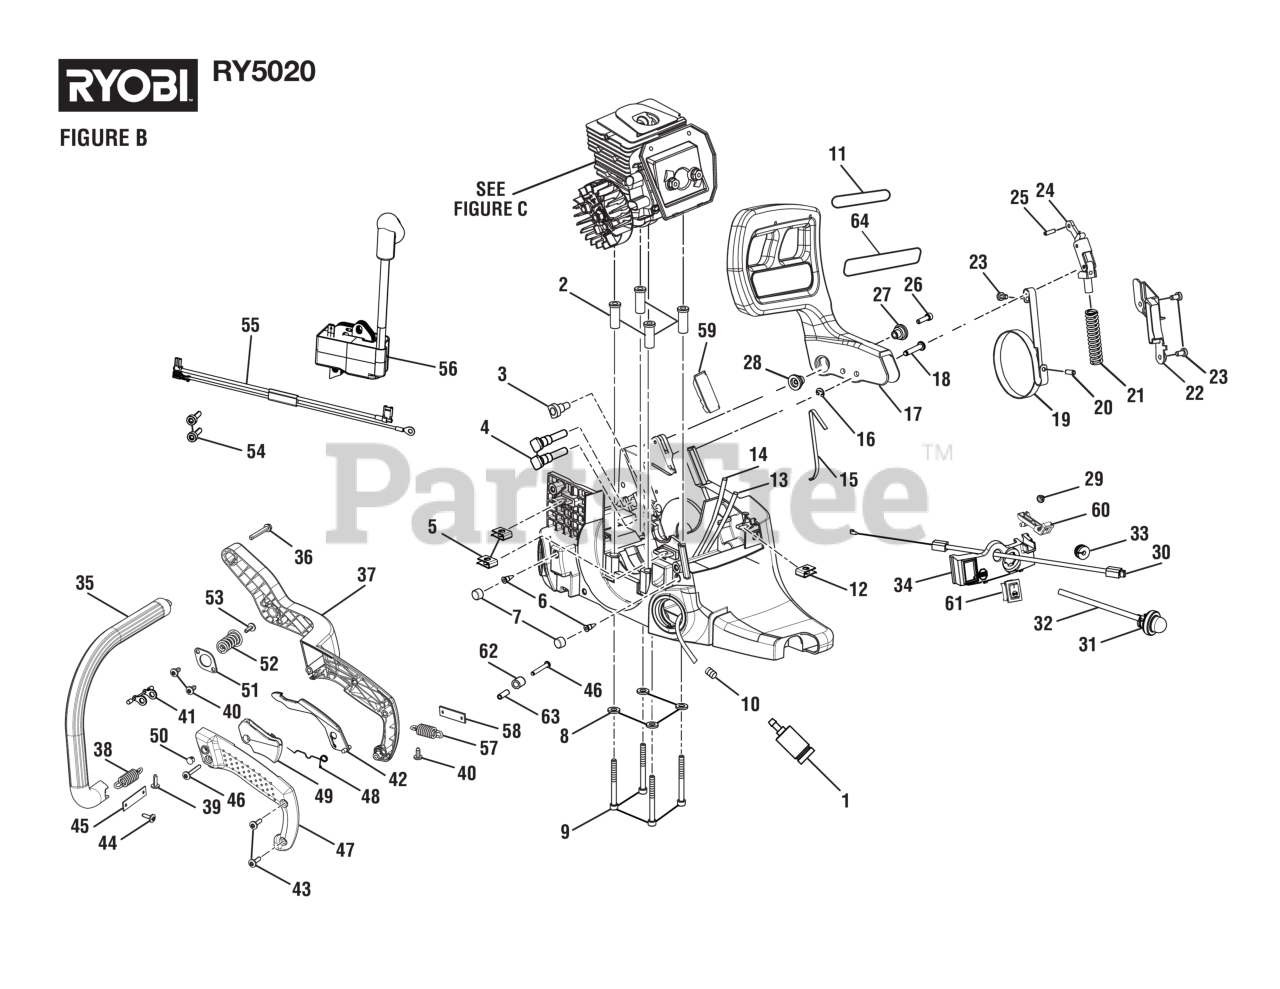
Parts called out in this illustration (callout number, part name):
1	Fuel Filter
2	Spacer Insert
3	GROMMET, OIL OUTLET
4	Control Panel, Black
5	Speed Nut ("U"-type)
6	Front Handle, Black
7	Front Handle, Gray
8	Washer (ID5.8 x OD11.5 x 1.7t)
9	Screw (10-24 X 2 in. Soc. Cap Hd.)
10	Filter Spring Clamp
11	Pull To Release Brake Label
12	Screw (10-14 x 1/2 in.)
13	Inlet Tubing (166 mm)
14	Cupped Washer
15	Screw (10-14 x 3/4 in.)
16	Screw (10-14 Thread Twin Helix)
17	Hand Guard Assembly
18	HAND GUARD ACTUATING PIN
19	Chain Brake Band Kit
20	Roll Pin (Big)
21	SPRING, COMPRESSION
22	Chain Brake Cover
23	Screw (#8-16 x 5/16 in., T25 Torx Pan Hd. T.F.)
24	Chain Brake Link Assembly
25	Spring Pin (Small)
26	Screw (8-32 X 5/8 in. Hex Soc. Hd.)
27	Screw (10-24 x 5/8 in.)
28	Screw (8-32 x 5/8 in.)
29	Ignition Switch Harness
30	THROTTLE CABLE
31	Primer Bulb
32	Primer Tubing (64 mm)
33	Grommet, Wire Harness (Split)
34	Control Panel
35	Front Handle, Black
36	SCREW (12-14 x 1-1/2 in.)
37	Rear Handle, Black
39	Screw, Truss Hd., Plastite (10-14 x 5/8")
40	Screw (10-14 x 1/2 in., Torx Truss Hd. T.F.)
41	Limiter (Upper Isolator Spring)
42	Trigger Release
43	Screws (10-14 x 3/4 in., T25 Torx Pan Hd. T.F.)
44	Screw (10-14 Thread Twin Helix)
45	Spring Retainer
46	SCREW (10-14 x 1-3/8 in.)
47	Handle Cover, Black
48	Torsion Spring
50	PLUG-PLASTIC
51	Isolator Plate
52	Isolator Spring
53	Screw (10-24 X 5/8 in. Torx Hd.)
54	Screw, Thread Form (8-32 x 5/8")
55	Ignition Switch Assembly
56	Ignition Module Assembly
58	Spring Retainer
60	Choke Lever
61	Stop Switch (Momentary Contact)
62	Rubber Bumper
63	Spacer (Spring Screw)
64	Chain Brake Label
